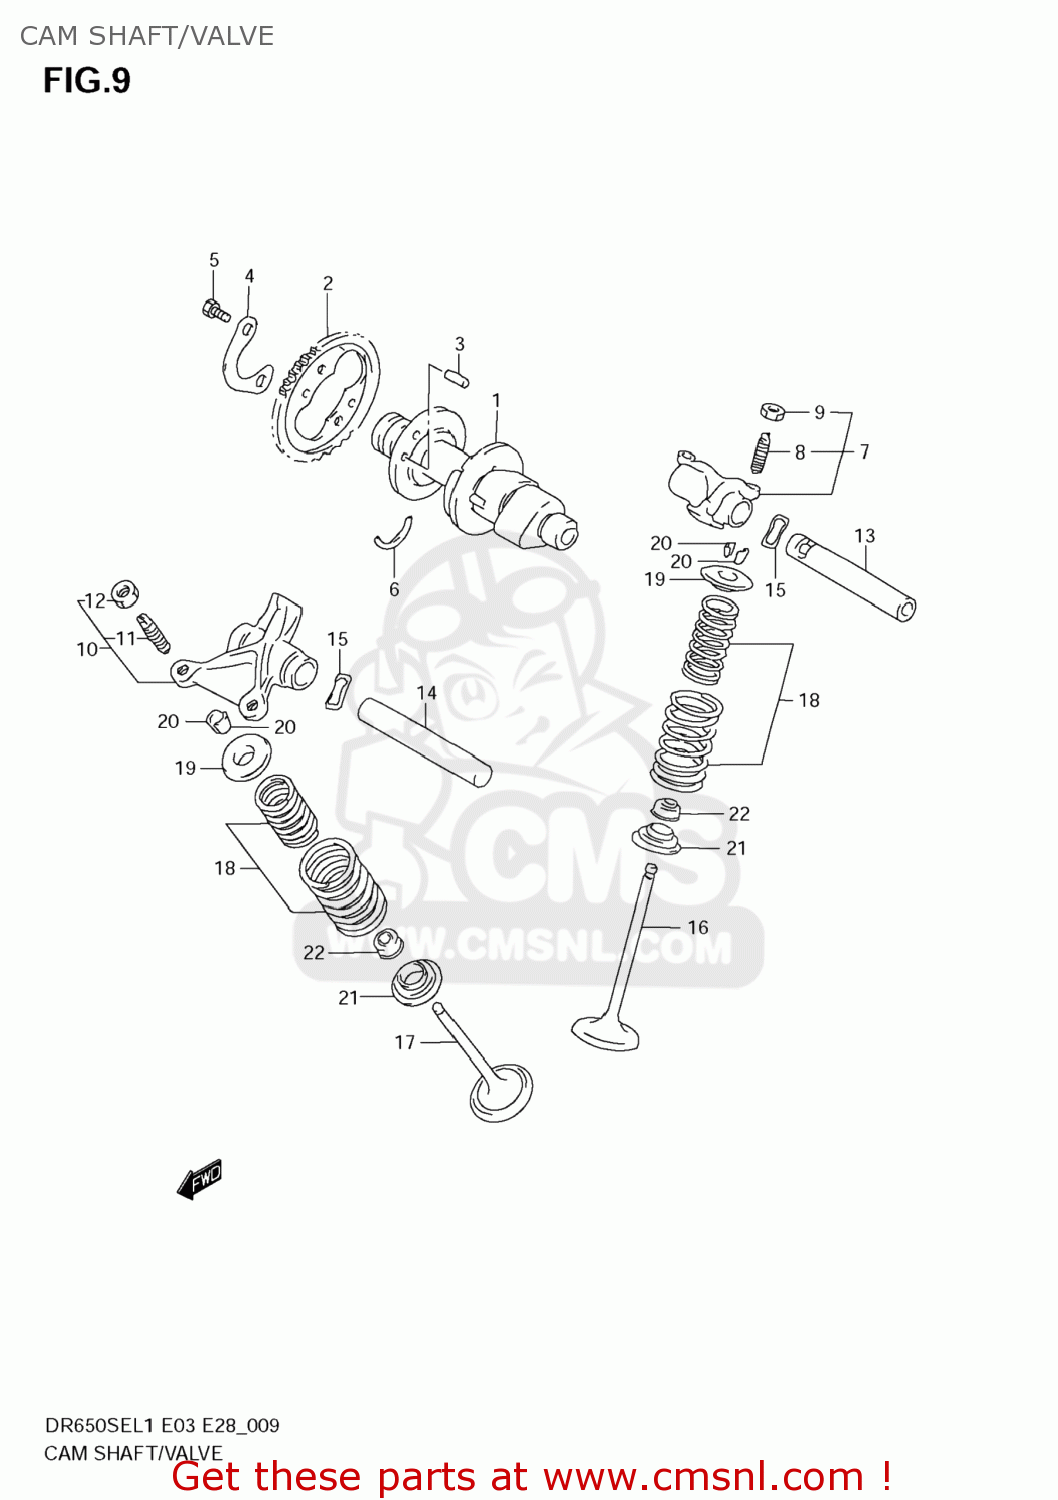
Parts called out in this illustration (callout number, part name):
1	CAMSHAFT
2	SPROCKET,CAMSHAFT(NT:38)
3	PIN(5X8)
4	WASHER,SPROCKET
5	BOLT(6X10.5)
6	C RING
7	ARM,VALVE ROCKER INTAKE
8	SCREW,TAPPET ADJUSTING
9	NUT,ADJUSTING SCREW
10	ARM,VALVE ROCKER EXHAUST
11	SCREW,TAPPET ADJUSTING
12	NUT,ADJUSTING SCREW
13	SHAFT,VALVE ROCKER ARM INTAKE
14	SHAFT,VALVE ROCKER ARM EXHAUST
15	WASHER
16	VALVE,INTAKE
17	VALVE,EXHAUST
18	SPRING SET,VALVE
19	RETAINER,VALVE SPRING
20	COTTER,VALVE
21	SEAT,VALVE SPRING
22	SEAL,OIL(5.5X11X8.2)
